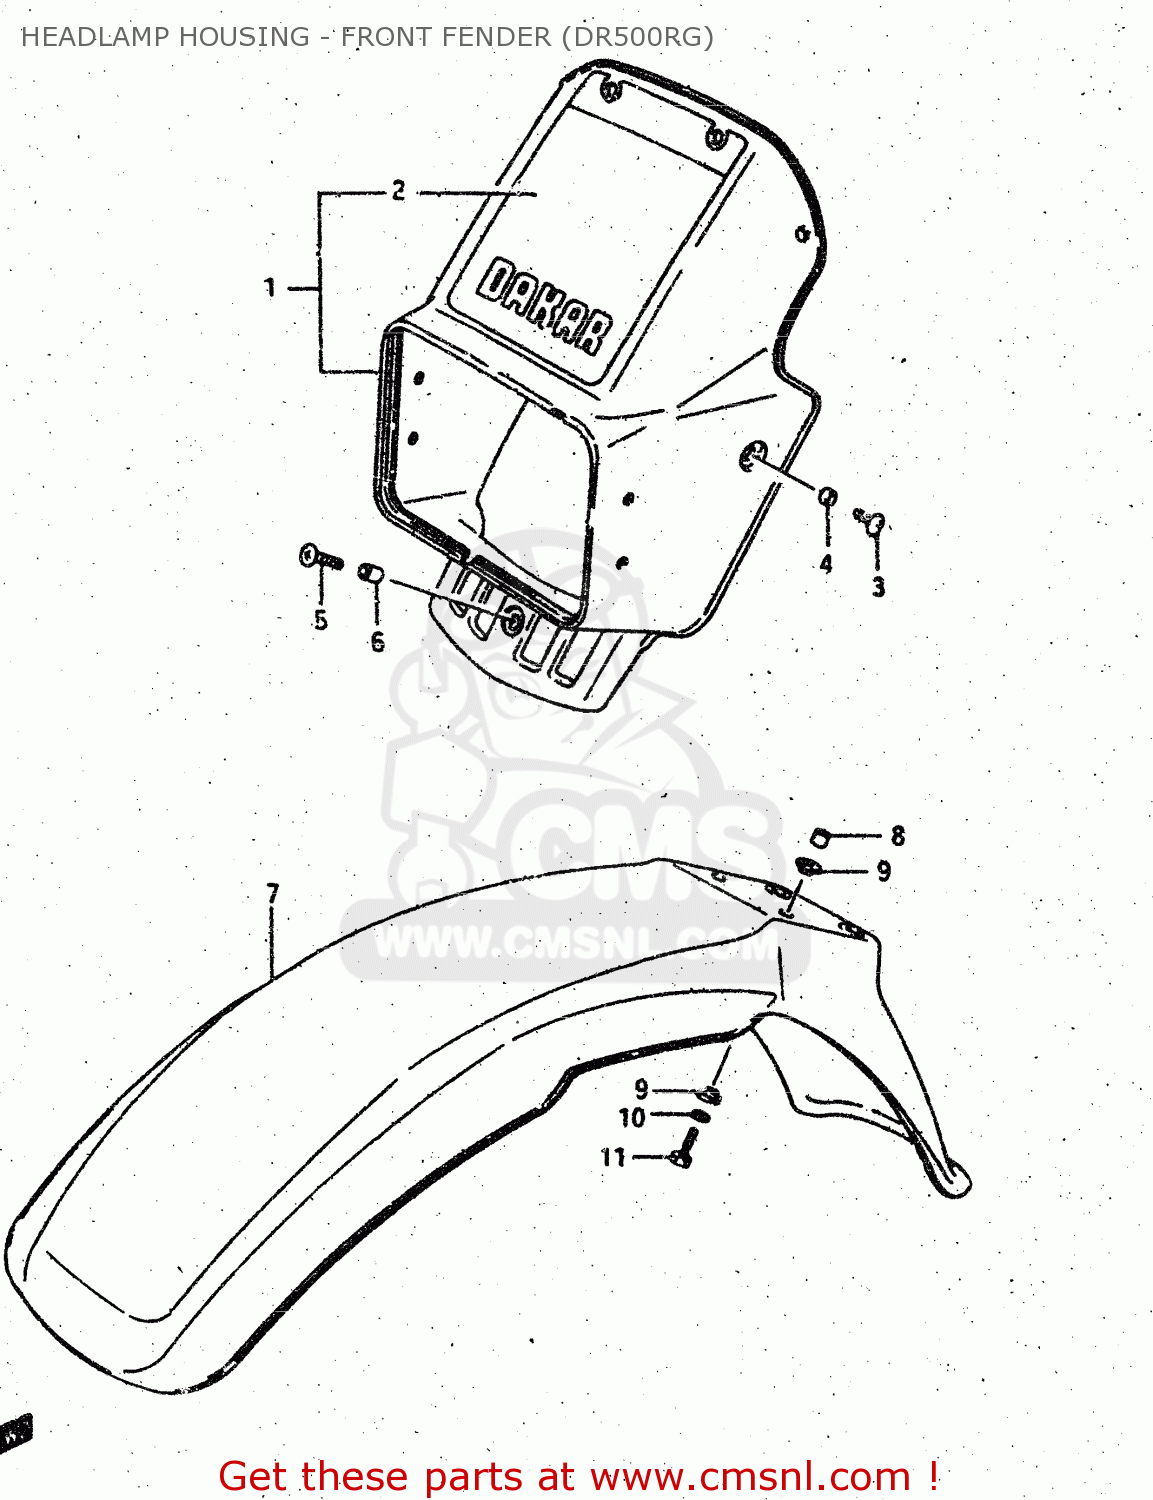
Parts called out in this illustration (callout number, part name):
1	COVER, HEADLAMP (WHITE)
2	TAPE SET
3	SCREW 6X12
4	SPACER (6.1X8X3.5)
5	SCREW, CENTER
6	SPACER (6.1X8X12)
7	FENDER, FRONT (WHITE)
8	SPACER(6.1X9X7.5)
9	SPACER
10	WASHER,LOCK
11	BOLT
